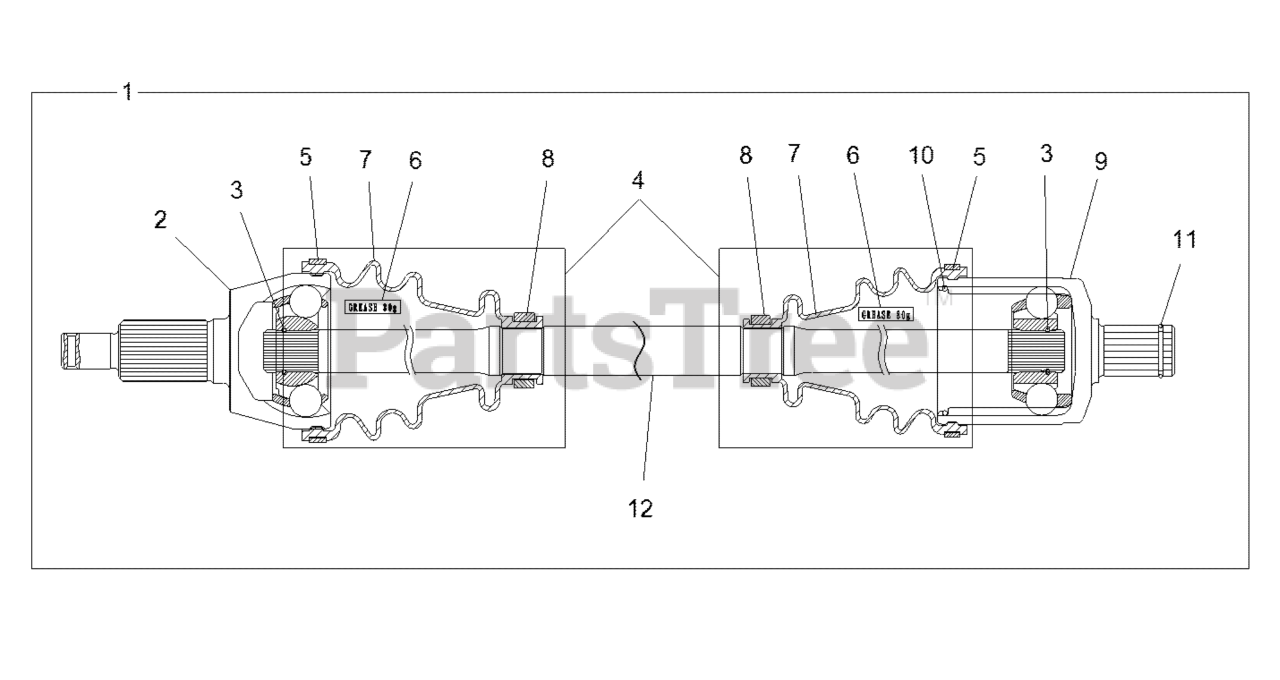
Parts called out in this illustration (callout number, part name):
1	ASM-HALF SHAFT,FRONT,LT
2	JOINT-CV,OUTER
3	CIRCLIP-1.8X22.2(PR-3011)
4	KIT-BOOT,PLUNGING JNT(PR-8062)
5	CLAMP-LARGE(PR-2019)
6	GREASE(K575/VW738)
7	BOOT(PR-0015)
8	CLAMP-SMALL(PR-0016)
9	JOINT-CV,INNER
10	CIRCLIP-2.0X61.7(PR-2016)
11	CIRCLIP-1.6X24.4(PR-2025)
12	SHAFT,23.5(PR-315)
